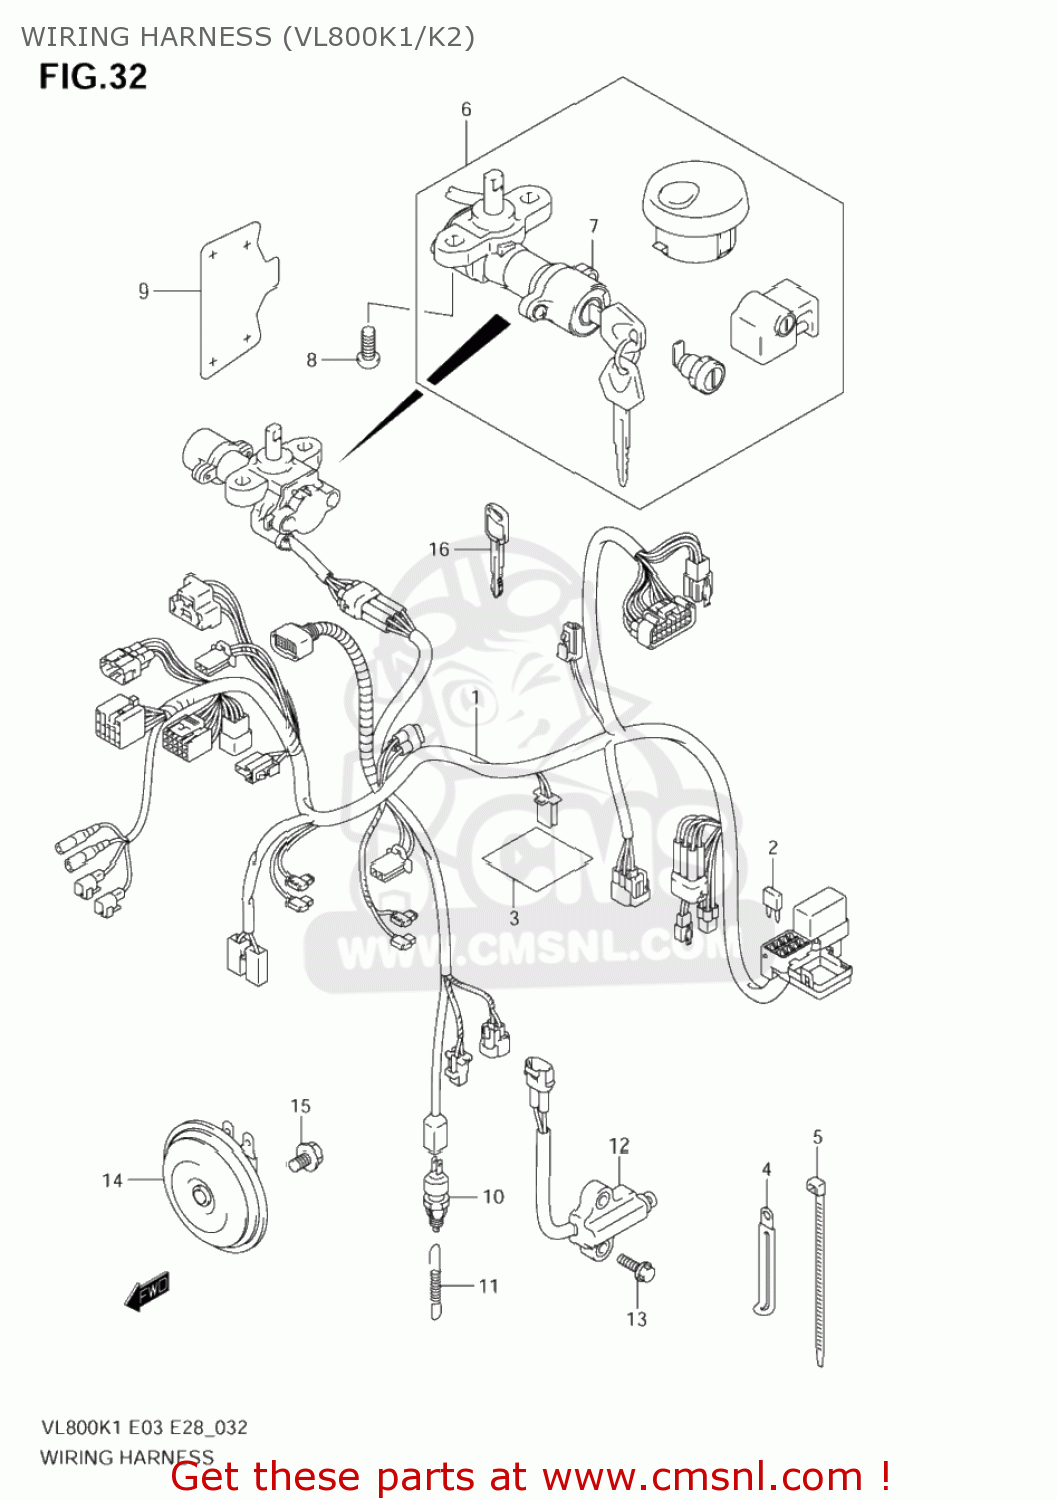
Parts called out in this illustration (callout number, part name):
1	HARNESS,WIRING
2	FUSE(10A)
3	PROTECTOR,WIRING HARNESS
4	CLAMP(L:80 T:1.0)
5	CLAMP(L:90)
6	LOCK SET
7	LOCK ASSY,STEERING
8	BOLT(8X20)
9	PROTECTOR,IGNITION SWITCH
10	SWITCH ASSY,STOP LAMP
11	SPRING
12	SWITCH ASSY,SIDE STAND
13	BOLT
14	HORN ASSY
15	BOLT
16	KEY,BLANK
